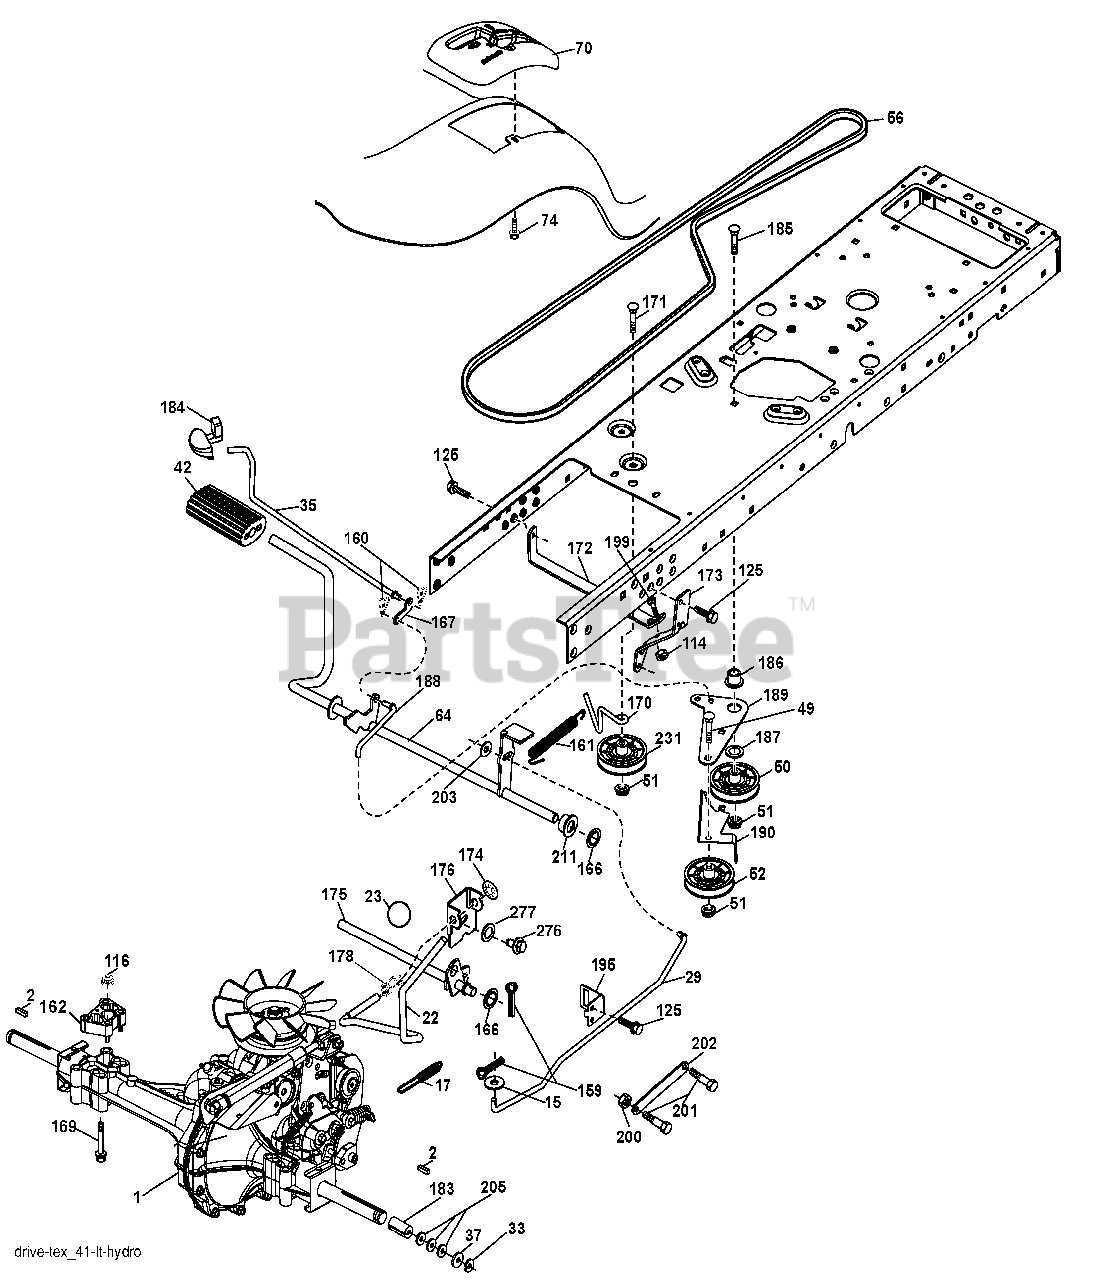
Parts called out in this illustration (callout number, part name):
1	Transaxle, Hydro Gear 351-0510 (See Transaxle Breakdown)
2	Key Square
15	Washer 13/32 x 13/16 x 16 Ga.
17	Spring, Brake
22	Rod Shift
23	Knob
29	Rod, Brake
33	Ring E
35	Rod, Brake, Park
37	Washer 25/32 x 1-1/4 x 16 Ga.
42	Cover, Foot Pedal
49	Bolt
50	Pulley Idler Flat
51	Lock Nut 3/8-16
52	Idler V-Groove 910" Offset
56	V-Belt, Drive
64	Shaft Asm. Pedal Brake Control
70	Console
74	Screw 1/4 x 1/2
114	Nut Lock 5/16-18 UNC
116	Nut Lock Hex Flange 5/16-18
125	Screw 5/16-18 x 3/4
159	Pin Cotter 1/8 x 3/4
160	Retainer Clip
161	Spring, Return, Clutch
162	Spacer Transaxle
166	Nut Push .625
167	Latch Brake Parking
169	Bolt 5/16-18 x 3.75
170	Keeper Belt Centerspan
171	Bolt
172	Strap Torque RH
173	Strap Torque LH
174	Nut Push
175	Shaft Asm Shift
176	Arm Clevis Rod Shift
178	Spring Shift
183	Spacer Axle
184	Handle Parking Brake
185	Bolt
186	Spacer Retainer
187	Washer
188	Link Clutch Ground Drive
189	Bellcrank Ground Drive
190	Keeper Bellcrank Ground Drive
195	Bracket Brake Rod
199	Bolt 5/16-18 UNC x 1
200	Nut Centerlock 5/16-18 UNC
201	Bolt Shoulder 5/16-18 UNC
202	Link Transaxle
203	Washer 11/32 x 11/16 x 16 Ga.
205	Washer 25/32 x 1-5/8 x 16 Ga.
211	Bushing
226	Bolt 7/16-14 x 1 Gr 5
227	Washer Serrated
231	Idler V-Groove 1.688" Offset
